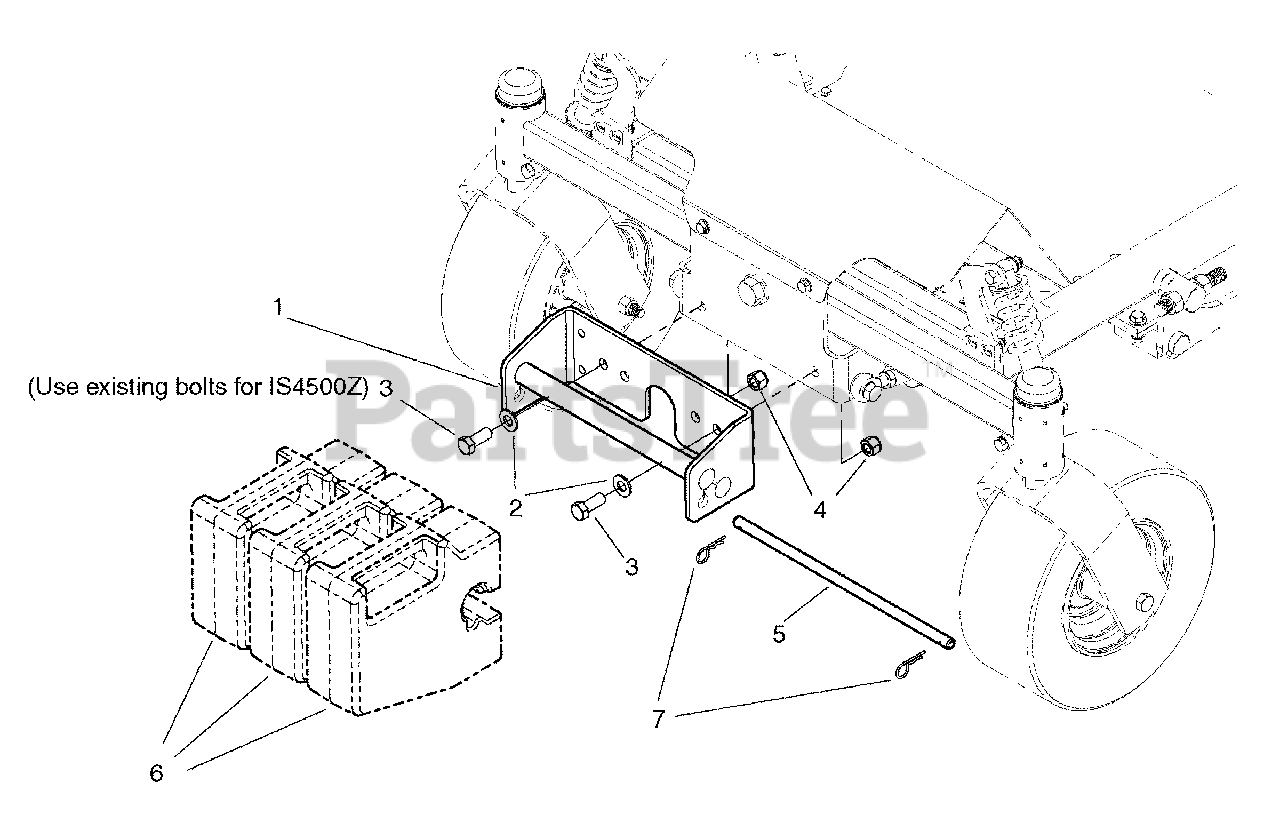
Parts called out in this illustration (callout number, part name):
1	WEIGHT MOUNT
2	WASHER, 1/2" SAE
3	BOLT, 1/2-20 x 1-1/4
4	NUT, 1/2-20 Hex Nylon Lock
5	WEIGHT LOCK ROD
6	WEIGHT, 50 lbs.
7	HAIR PIN
